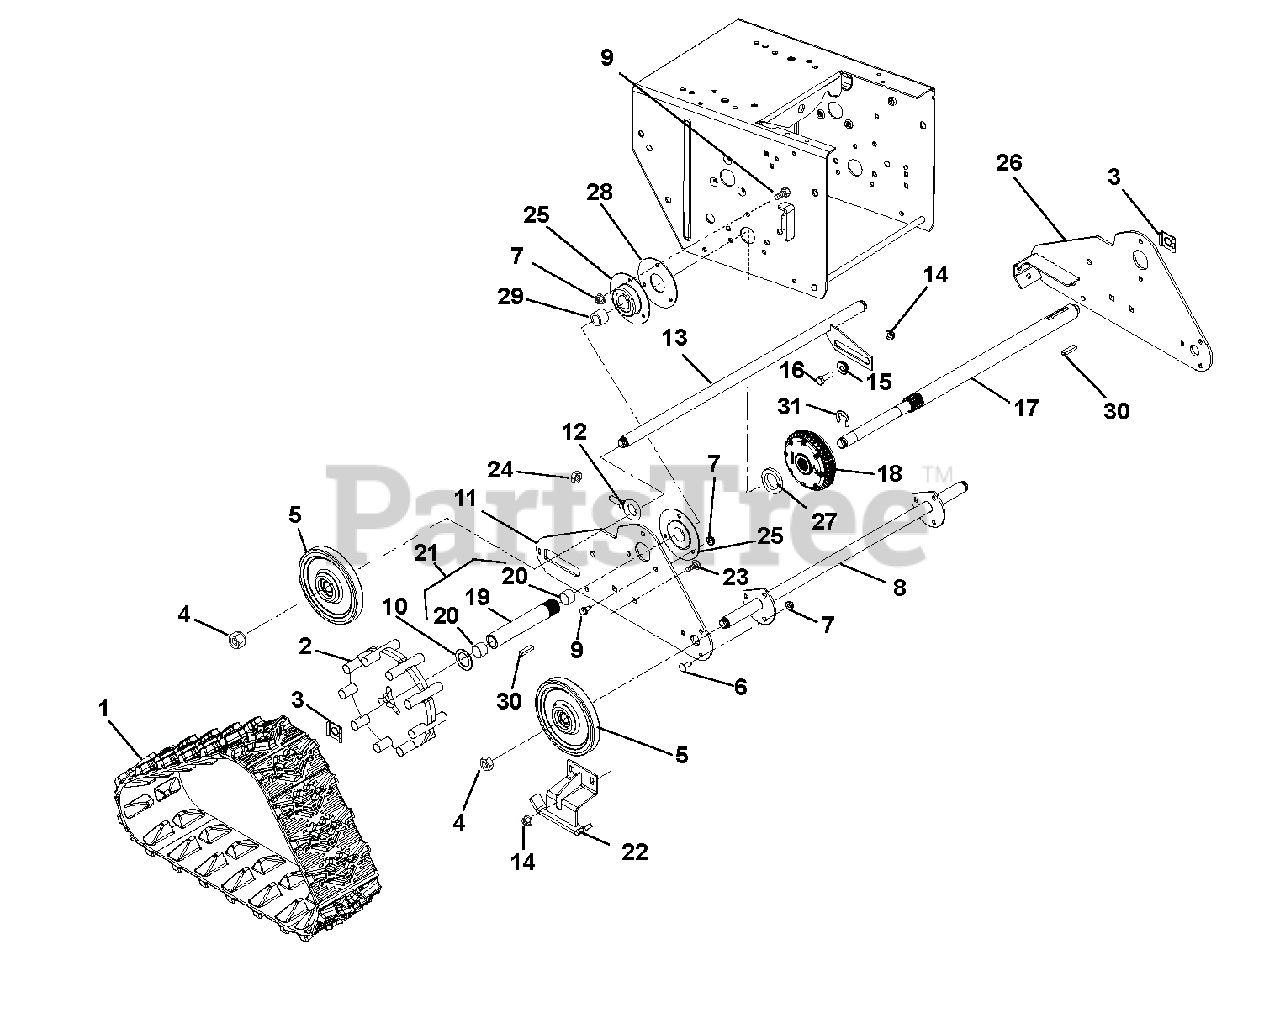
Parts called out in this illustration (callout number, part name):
1	TRACK, RUBBER
2	WHEEL, MACHINED DRIVE
3	CLIP, SNAP .625 DIA
4	@NUT-LK-NYL .625-18 YWZC
5	WHEEL, BOGIE - SINGLE BEARING
6	@BLT-RDHDSQNK .25-20X.75 G5YZ
7	@NUT-LK-CTR-FLG .25-20 YWZC
8	AXLE, FRONT - PRO
9	@BLT-HEX .25-20X.75 GR5 YWZC
10	WSHR-FL-STL 1.010X1.505X.062YZ
11	SIDE PLATE, RH-TRACK
12	BLT-EYE .375-16X.880 YWZC
13	AXLE, REAR - PRO TRACK
14	@NUT-LK-TOP-FLG .31-18 YWZC
15	BSHG-FLG .325X.499X.3X.875
16	@BLT-HEX .31-18X1.00 GR5 YWZC
17	AXLE, LONG-PRO AUTO DIFF
18	DIFFERENTIAL, AUTOMATIC
19	AXLE, SHORT-TRACK DIFFERENTIAL
20	BSHG-SLV .706X.764X.75 BRZ
21	AXLE, SHORT-TRACK W/BUSHINGS
22	RUNNER, GUIDE-TRACK
23	@BLT-RDHDSQNK .31-18X.75 G5YZ
24	NUT-LK-CTR-FLG .38-16 YWZC
25	BRG-FLG 1.003/1.000 3 BOLT
26	SIDE PLATE, LH-TRACK
27	WSHR-FL-STL- 1.062X2.0X.134 YZ
28	PLATE, BEARING SPACER
29	BSHG-SLV, 1.012X1.125X1.00
30	KEY-RECT .25X.188X1.00
31	RG-RTNG-EXT .625X.042
